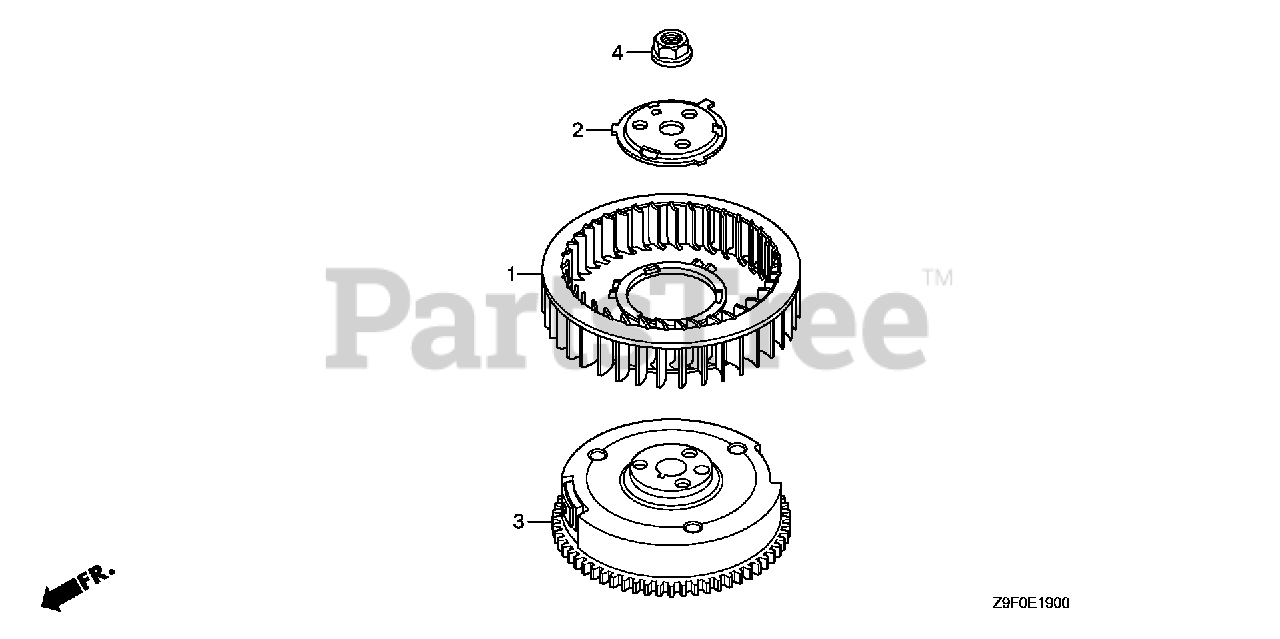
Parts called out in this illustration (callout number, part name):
1	FAN, COOLING
2	PLATE, COOLING FAN SETTING
4	NUT, SPECIAL (20MM)
